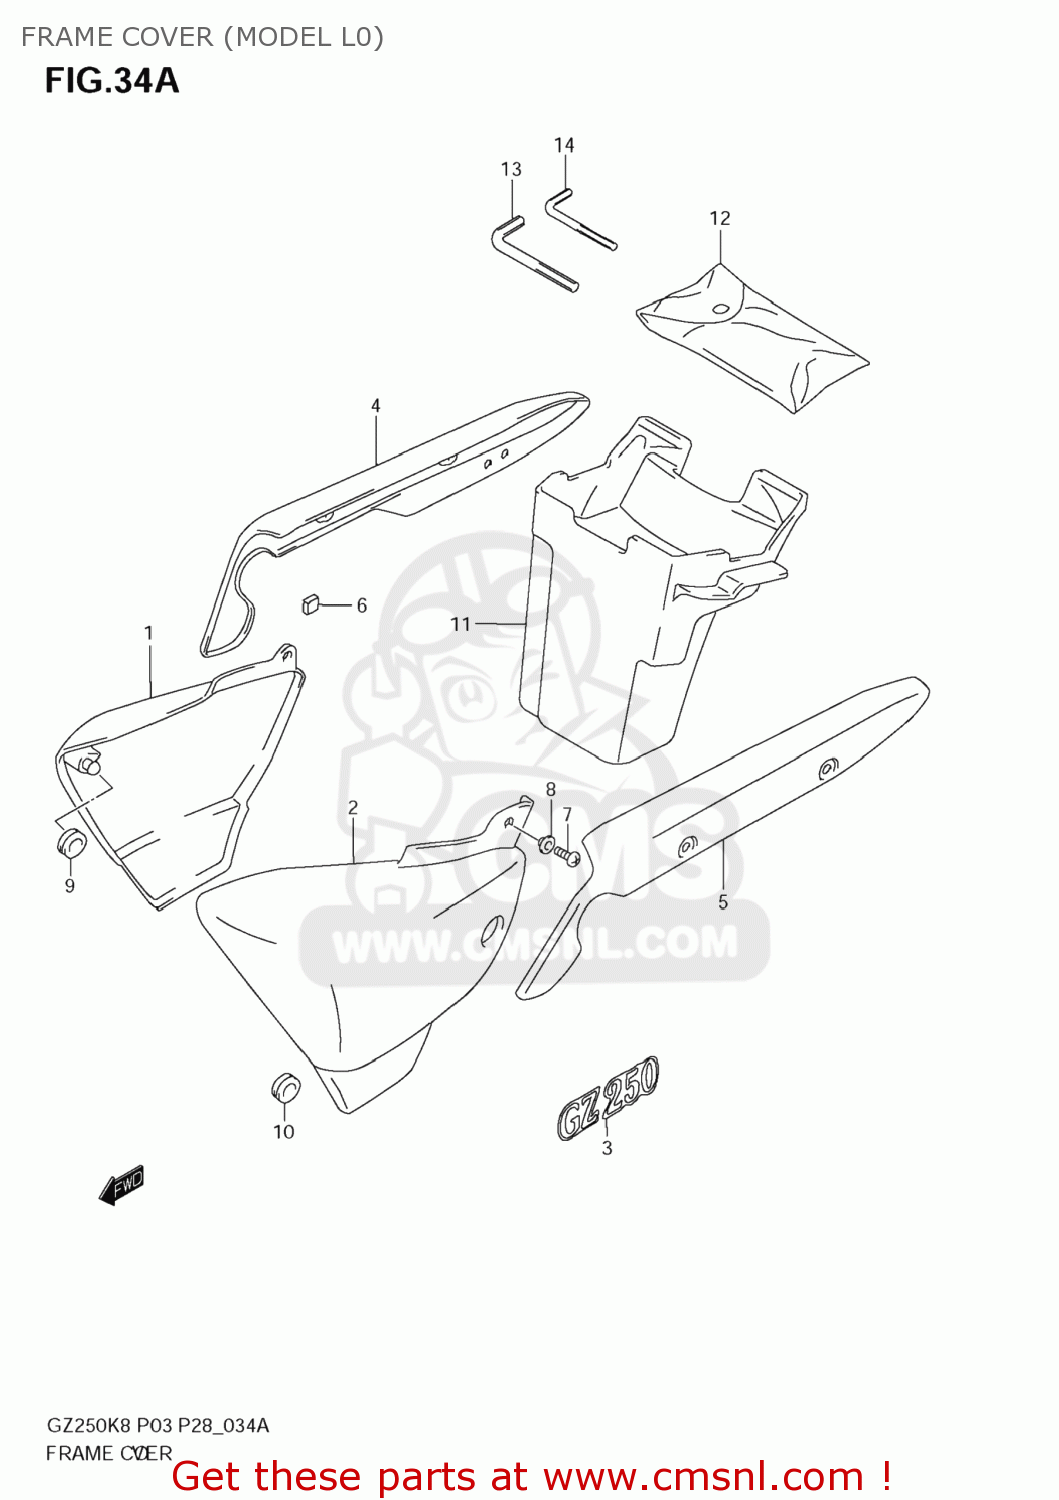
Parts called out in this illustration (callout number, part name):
1	COVER,FRAME
2	COVER,FRAME
3	EMBLEM,COVER
4	COVER, FRAME REAR RH
5	COVER, FRAME REAR LH
6	CUSHION
7	SCREW
8	WASHER
9	CUSHION
10	CUSHION
11	BODY, LUGGAGE BOX
12	TOOL ASSY
13	SPANNER,HEXAGON(6)
14	SPANNER,HEXAGON(4)
